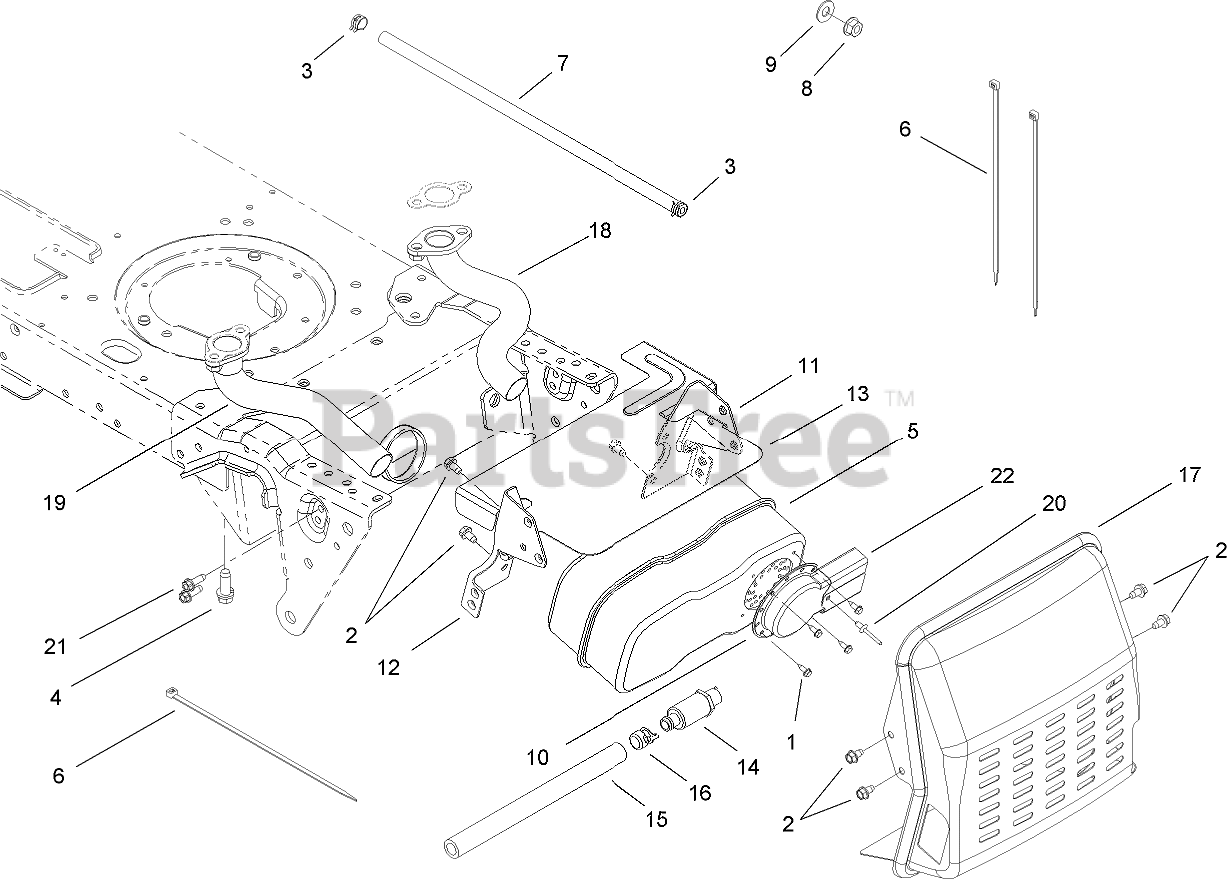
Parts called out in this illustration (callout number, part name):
1	SCREW-HWHTF
2	SCREW-HWHTF
3	CLAMP-HOSE
4	SCREW-TAP
5	MUFFLER-INLET, DUAL
6	TIE-CABLE
7	HOSE-FUEL
8	NUT-LOCK, FLANGE
9	WASHER-FLAT
10	DEFLECTOR-MUFFLER
11	BRACKET-MUFFLER, LH
12	BRACKET-MUFFLER, RH
13	SHIELD-HEAT
14	DRAIN-OIL
15	HOSE-DRAIN
16	CAP-DRAIN, OIL
17	MUFFLER SHIELD ASM
18	PIPE-EXHAUST, LH
19	PIPE-EXHAUST, RH
20	RIVET-POP
21	SCREW-TAP
22	DEFLECTOR-MUFFLER, LONG
